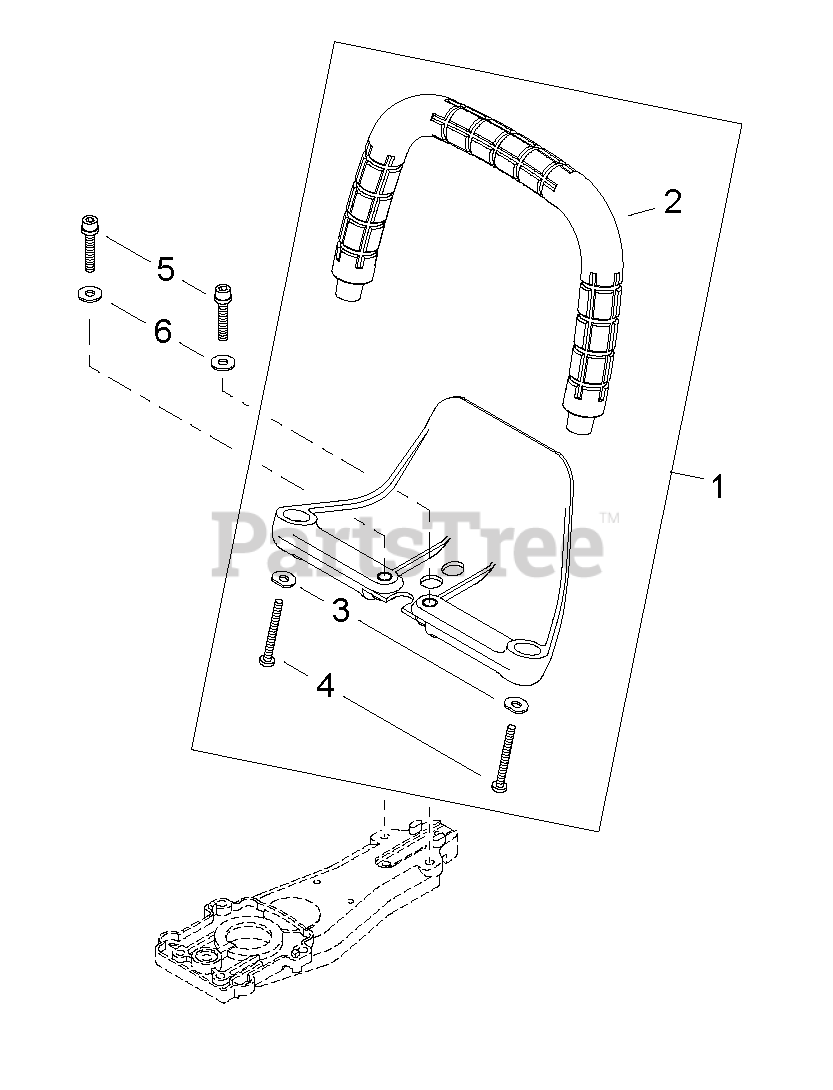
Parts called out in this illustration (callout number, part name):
1	HANDLE ASSY - FRONT
2	HANDLE - FRONT
4	SCREW - 5 -- TAPPING
5	SCREW - 6X35
